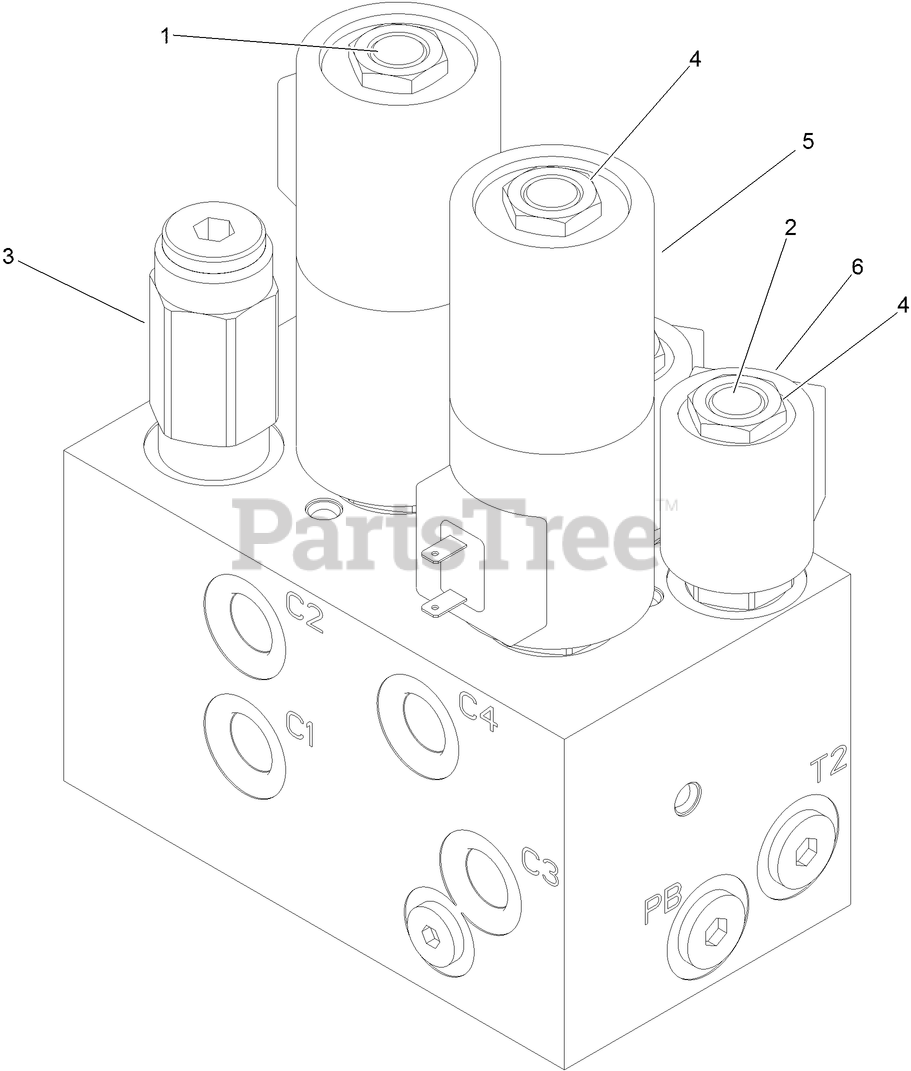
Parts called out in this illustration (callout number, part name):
1	VALVE,3 POSITION,4 WAY,OPEN CENTER
2	VALVE,2 WAY,NORMALLY CLOSED
3	VALVE,RELIEF(1250 PSI)
4	NUT,COIL,SOLENOID VALVE HYD01637/07029
5	COIL,HYDRAULIC VALVE (12V SYSTEM) SAE#10
6	COIL,HYDRAULIC VALVE (12V SYSTEM) SAE#8
